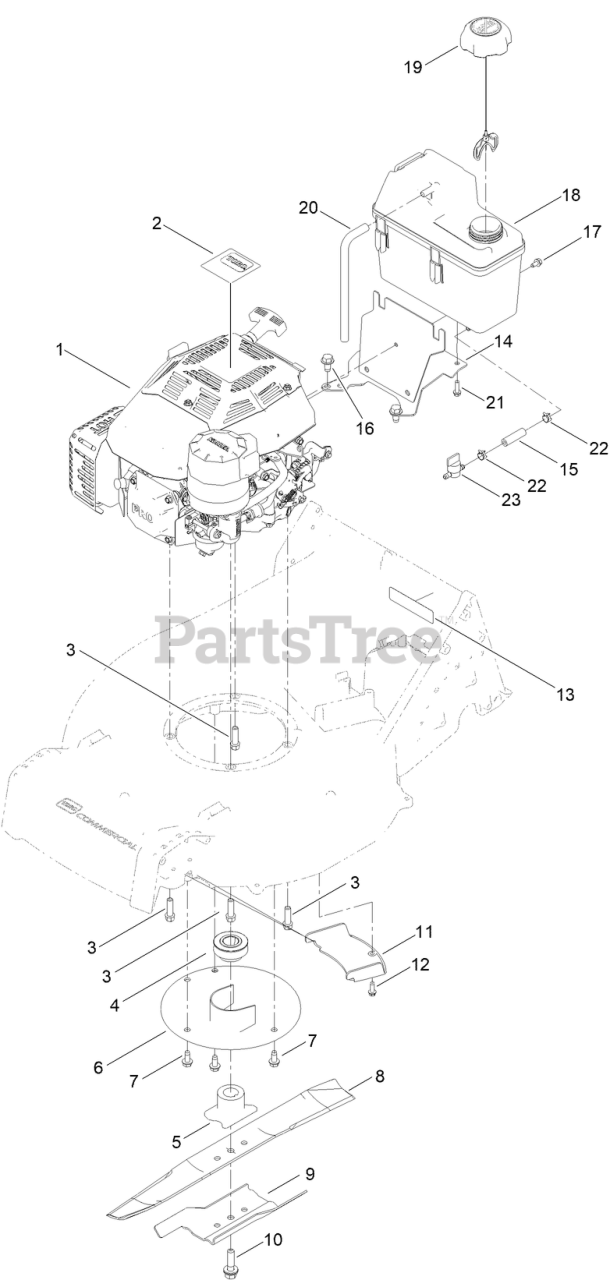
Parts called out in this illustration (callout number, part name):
1	ENGINE-KOHLER
2	DECAL-KOHLER
3	SCREW-TAPTITE
4	PULLEY-DRIVER
5	DRIVER-BLADE
6	PROTECTOR-CRANKSHAFT
7	SCREW-HWHTF
8	BLADE-21IN, RECYCLING
9	ACCELERATOR-BLADE
10	BOLT-BLADE
11	COVER-BELT
12	SCREW-HWHTF
13	DECAL-ARRESTOR, SPARK
14	TANK MOUNT ASM
15	HOSE-FUEL
16	SCREW-HWH
17	SCREW-HWH
18	TANK-FUEL
19	CAP-FUEL
20	HOSE-VENT, CANISTER
21	SCREW-HWH
22	CLAMP-HOSE
23	VALVE-FUEL
